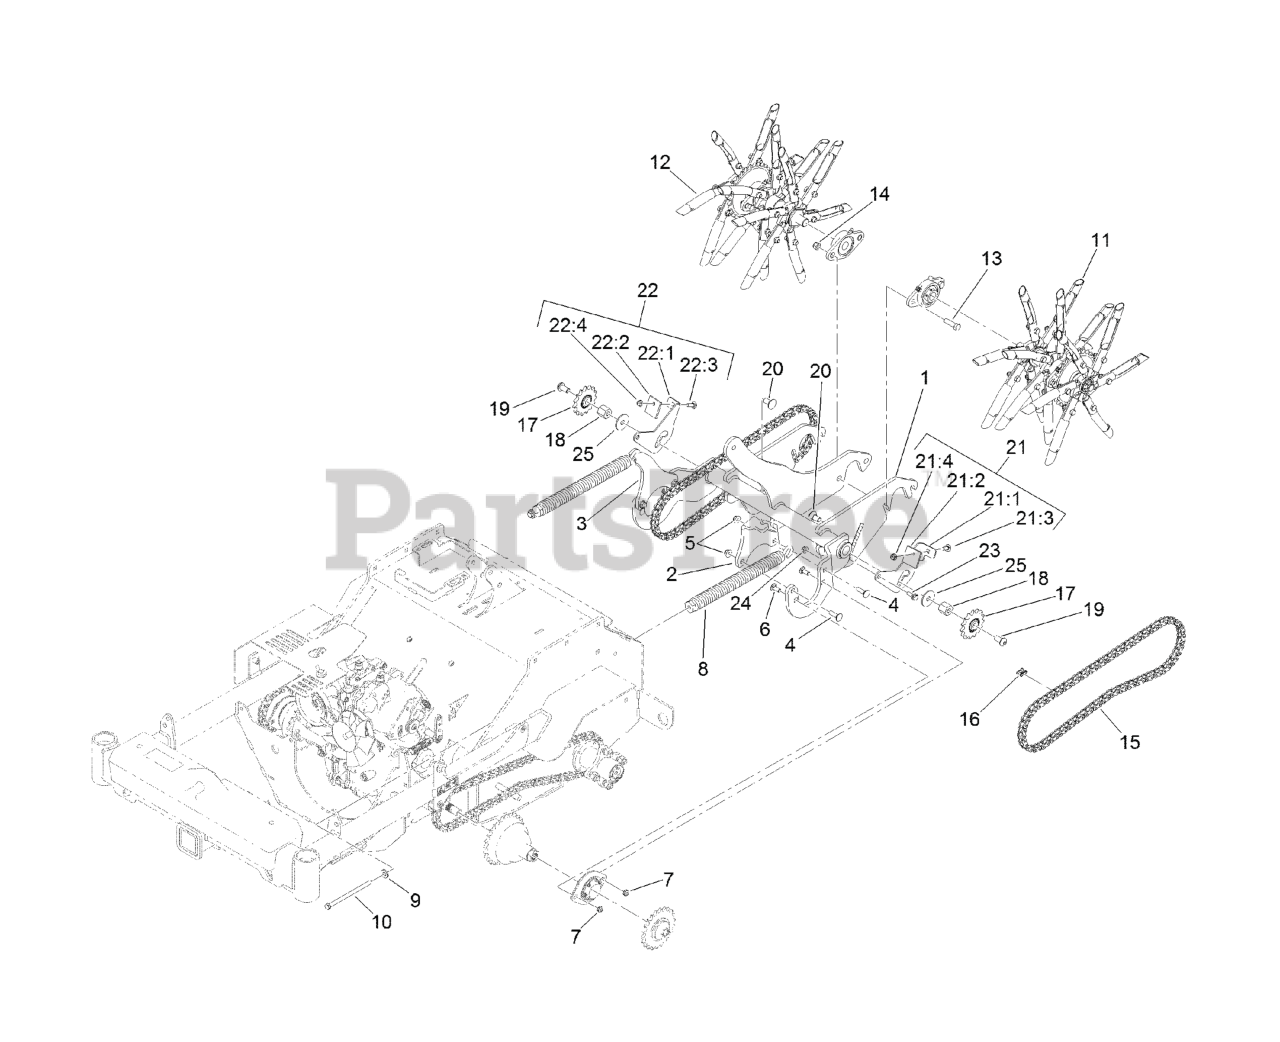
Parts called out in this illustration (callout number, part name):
1	LIFT-TINE
2	ARM-SPRING, LH
3	ARM-SPRING, RH
4	BOLT-CARR
5	NUT-HF, NI
6	BOLT-CARR
8	SPRING-EXTENSION
9	WASHER-BELLEVILLE
10	BOLT-TAP, HH
11	LH TINE WHEEL ASM
12	RH TINE WHEEL ASM
14	NUT-LOCK, NI
15	CHAIN-ROLLER
16	LINK-CONNECTING
17	SPROCKET-IDLER, 15T
19	SCREW- PAN SOCKET HEAD
20	SCREW-CARR
21	LH DEBRIS DEFLECTOR ASM
21:1	BRACKET-DEFLECTOR, DEBRIS
21:2	DEFLECTOR-DEBRIS
21:3	BOLT-CARR
21:4	NUT-HF, NI
22	RH DEBRIS DEFLECTOR ASM
22:1	BRACKET-DEFLECTOR, DEBRIS
22:2	DEFLECTOR-DEBRIS
22:3	BOLT-CARR
22:4	NUT-HF, NI
23	SCREW-SHOULDER
24	NUT-HF, NI
25	WASHER-FLAT
